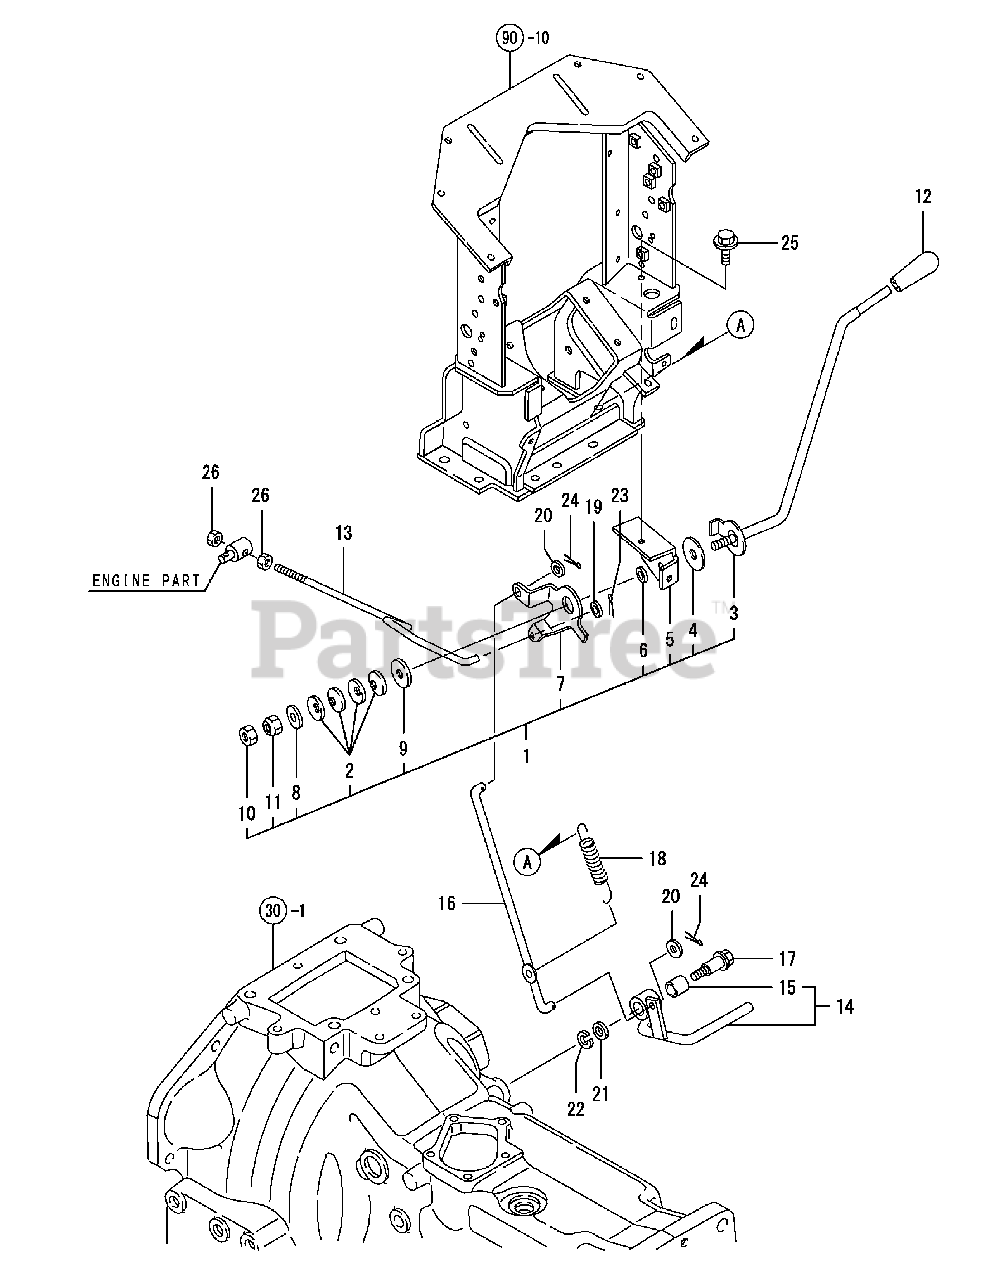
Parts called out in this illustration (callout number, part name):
1	LEVER KIT, CONTROL
2	WASHER 10, CONICAL
3	LEVER ASSY, CONTROL
4	PLATE, FRICTION
5	BRACKET, LEVER
7	LEVER,ACCELRTR.LINK
10	LOCK NUT M10 PLATED
12	KNOB, THROTTLE LEVER
13	ROD,ACCELERATOR
14	PEDAL, THROTTLE
16	ROD, THROTTLE LINK
18	SPRING, RETURN
19	WASHER 8, POLISHED
20	WASHER 8, POLISHED
21	WASHER 10,POLISHED
22	SPRING WASHER 10
23	COTTER PIN 2.5X30
24	COTTER PIN 2.5X30
25	BOLT M 8X 16 PLATED
